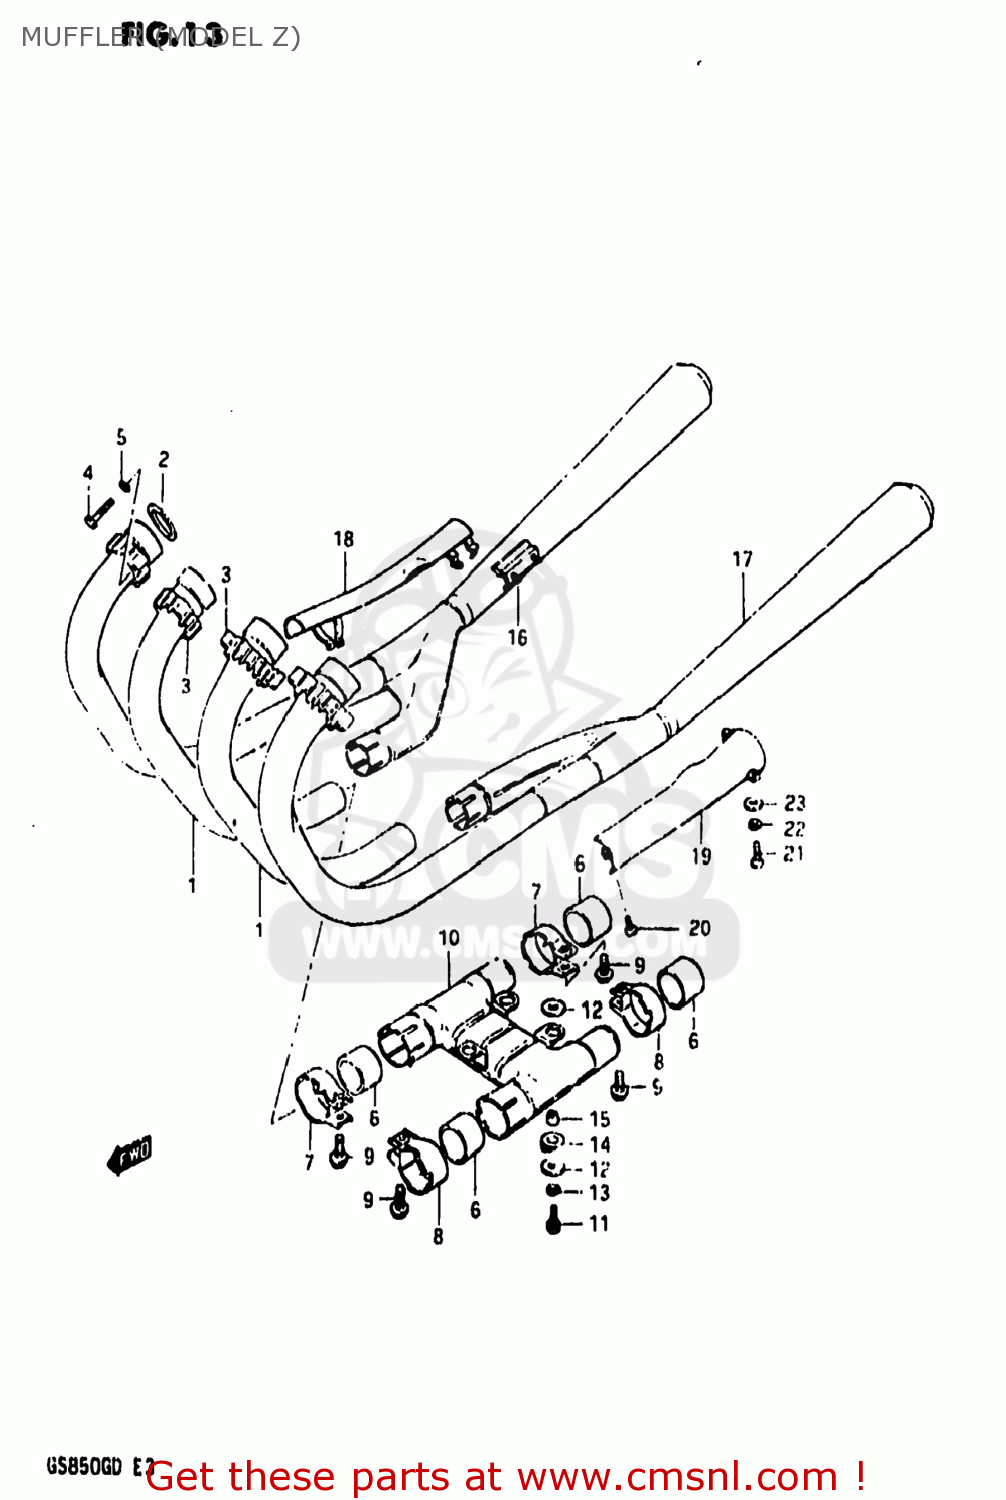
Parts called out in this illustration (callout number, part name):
1	PIPE,CENTER EXHAUST
2	GASKET,EXHAUST PIPE (NAS)
3	CLAMP,EXHAUST PIPE
4	BOLT
5	LOCK WASHER
6	CONNECTOR,MUFFLER
7	CLAMP,MUFFLER CONNECTOR,R
8	CLAMP,MUFFLER CONNECTOR,L
9	BOLT
10	BODY,PREMUFFLER
11	BOLT
12	WASHER (6.5X24X1.6)
13	LOCK WASHER
14	CUSHION
15	SPACER(6.5X10.5X6.5)
16	MUFFLER ASSEMBLY
17	MUFFLER ASSEMBLY
18	COVER,MUFFLER
19	COVER,MUFFLER,LEFT
20	SCREW
21	SCREW
22	LOCK WASHER
23	WASHER
